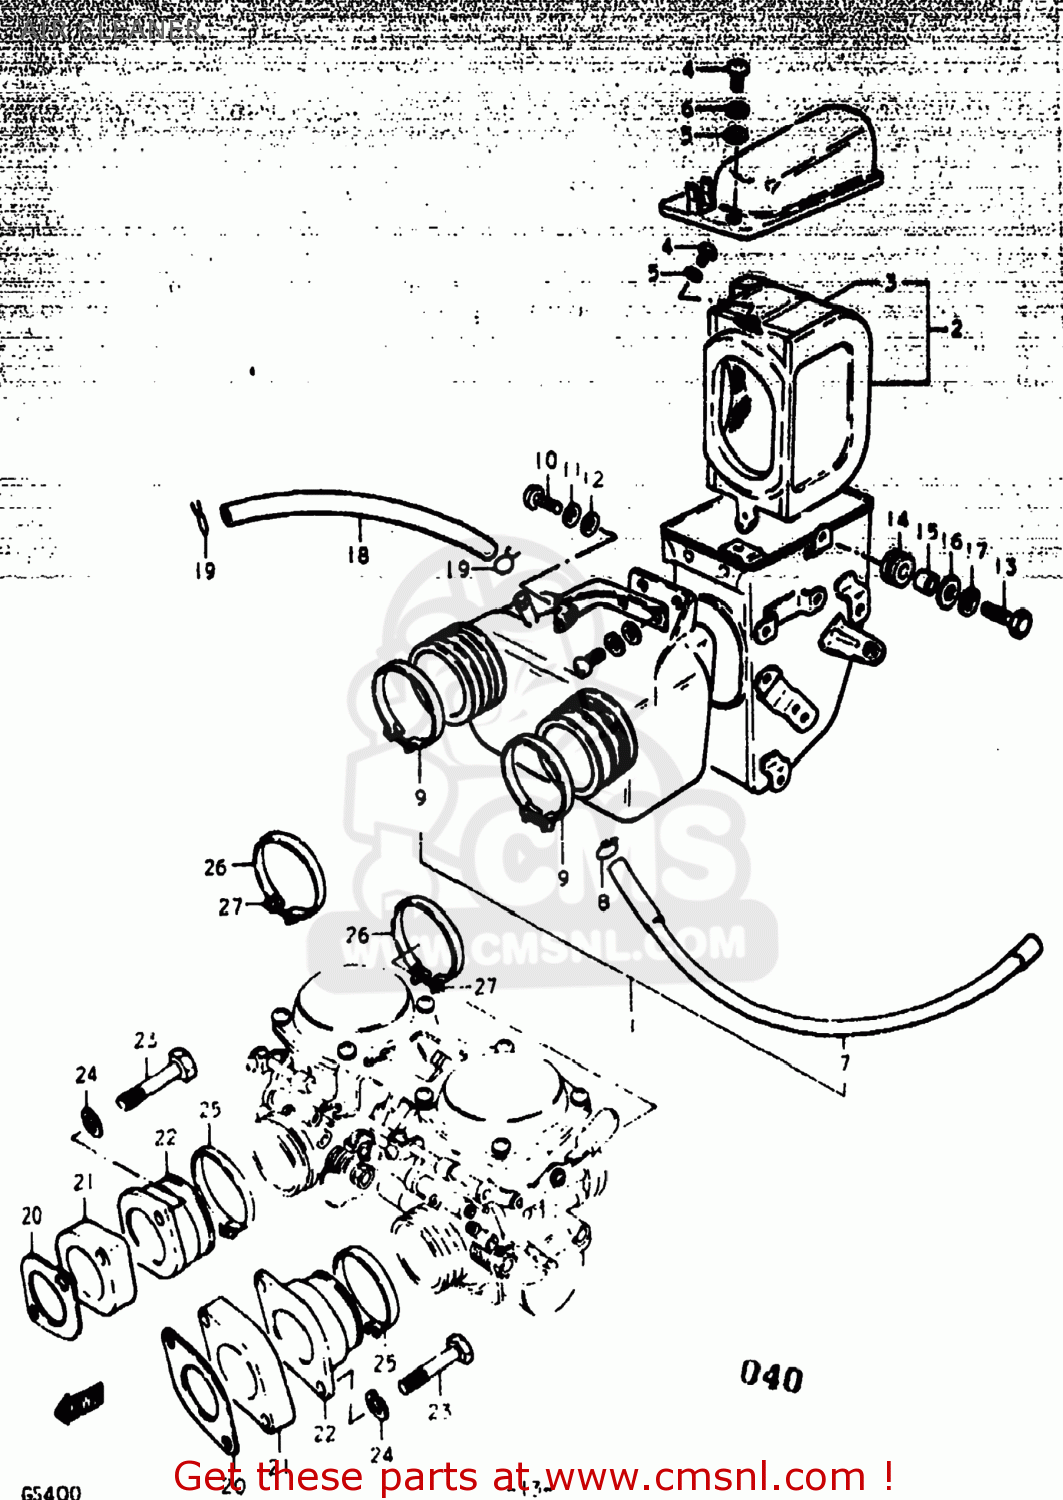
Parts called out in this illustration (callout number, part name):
1	CLEANER ASSEMBLY,AIR
2	FILTER ASSY
3	FILTER
4	SCREW
5	WASHER
6	LOCK WASHER
7	HOLDER,FILTER
8	HOSE,AIR CLEANER
9	CLAMP
10	SCREW 6X12
11	LOCK WASHER
12	WASHER 6MM
13	BOLT
14	CUSHION
15	SPACER (6.1X9X9)
16	WASHER
17	LOCK WASHER
18	HOSE
19	CLIP
20	GASKET,CARBURETOR (MCA)
21	INSULATOR,CARBURETOR
22	PIPE,INTAKE
23	BOLT
24	LOCK WASHER
25	CLAMP
26	CLAMP
27	SCREW TAPP.
